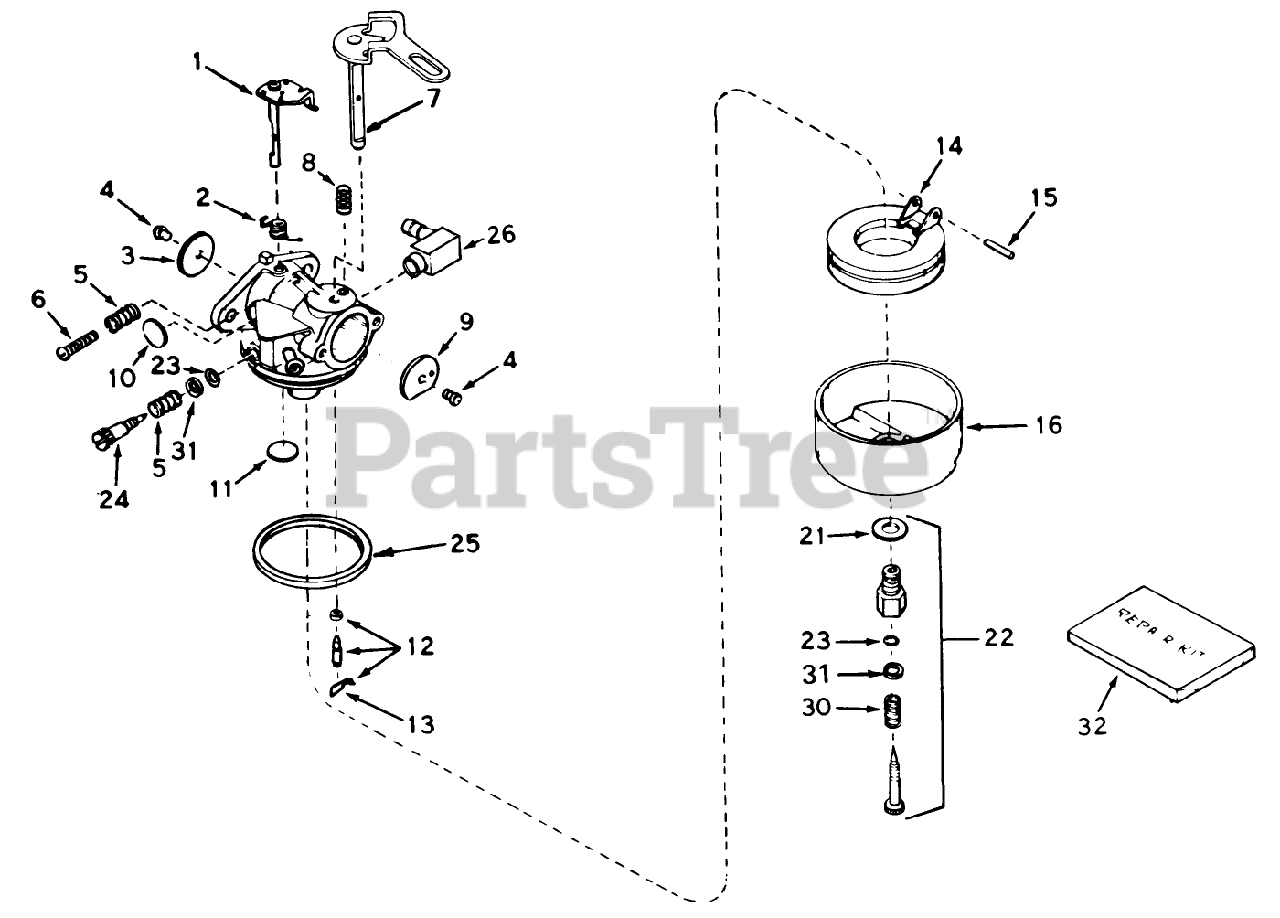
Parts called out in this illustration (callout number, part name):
1	Throttle Shaft and Lever ASM
2	Spring, Return
3	Shutter-Throttle
4	Screw-Shutter
5	Spring-Tension
6	Screw-Throttle Crack Screw / Idle Speed
7	Choke Shaft and Lever Asm
8	Spring-Positioning, Choke
9	Shutter-choke
10	Plug-Welch, Idle Mixture Well
11	Plug-Welch, Atmospheric Vent
12	Inlet Needle, Seat Clip Assy. (Incl. No. 13)
13	Clip-Spring
14	Float
15	Shaft-Float
16	Bowl-Float (no drain)
21	Washer-Bowl Nut
22	Adjustment Screw Assy., Main (Incl. Nos. 5A, 21 23)
23	ORing
24	Screw, Idle Adj.
25	O Ring-Bowl, Float
26	Fitting-Fuel
30	Spring
31	Washer
32	Repair Kit (Incl. items marked *)
